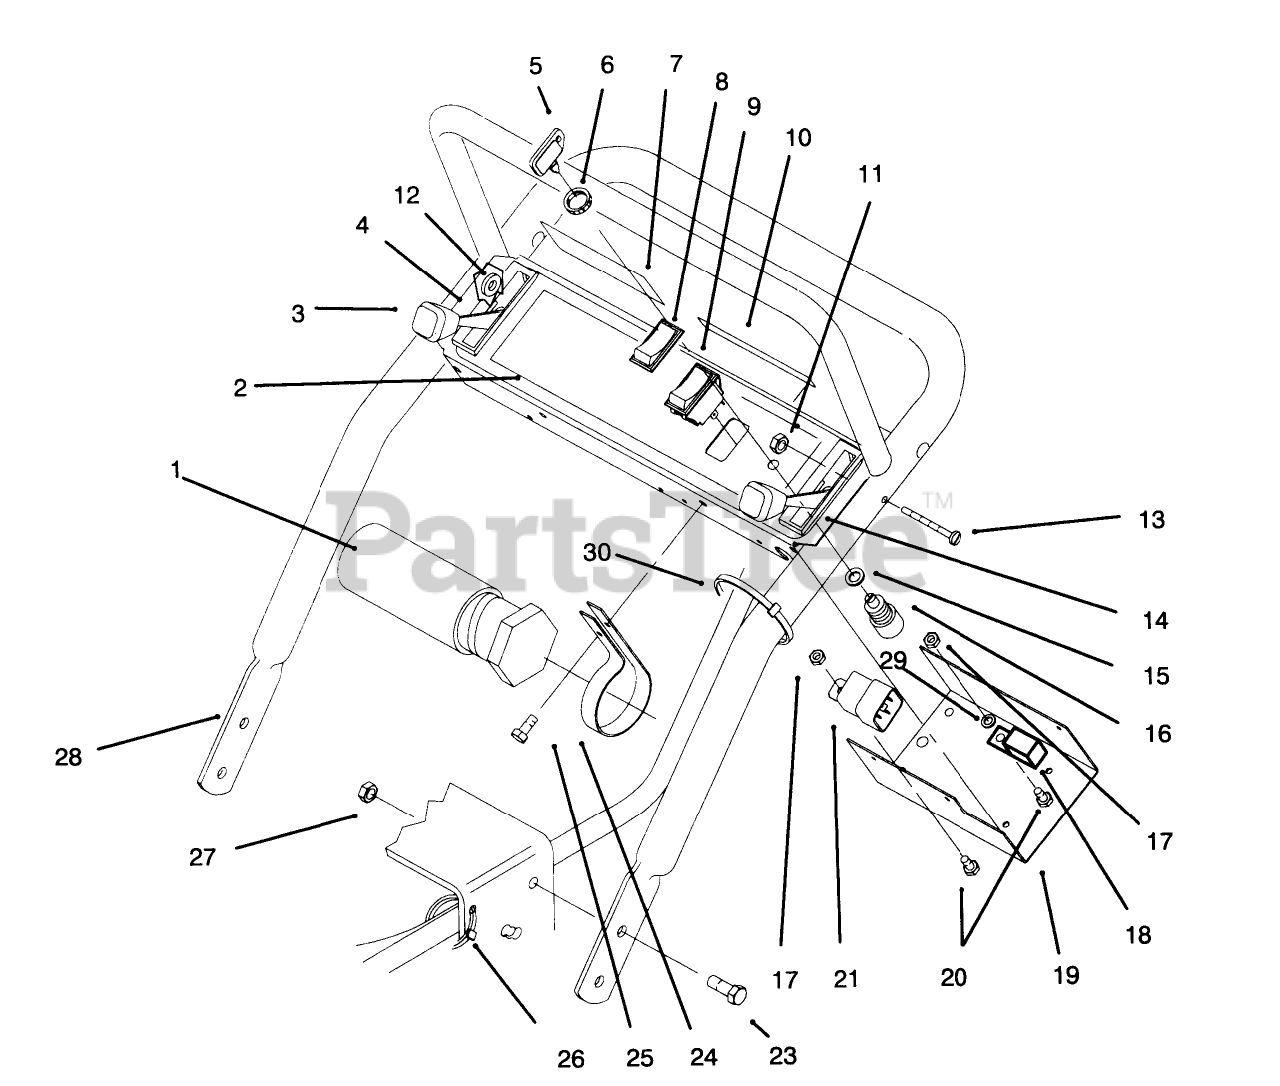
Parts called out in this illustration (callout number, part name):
1	TUBE-MANUAL
2	DECAL-CNTRL PANEL-30175
3	CONTROL - CHOKE
4	Panel-Control
5	KEY-IGNITION
6	NUT-HH
7	DECAL-INSTRUCTION, SAFETY
8	BOOT-SWITCH
9	Switch-Clutch (Incl. Ref. #8)
10	DECAL-INSTRUCTION
11	NUT-LOCK, NI
12	SPACER
13	SCREW-SHH
14	CONTROL - THROTTLE
15	WASHER-TOOTH, INTERNAL
16	Switch-Ignition (Incl. Ref. #5, 6, & 15)
17	NUT-LOCK, NI
18	Module
19	Panel-Bottom
20	SCREW-HH
21	RELAY
23	SCREW-HHF
24	CLAMP-R
25	SCREW-SHWH
26	TIE-CABLE
27	NUT-HF
28	Handle-Upper
29	Washer-Lock
30	TIE-CABLE
